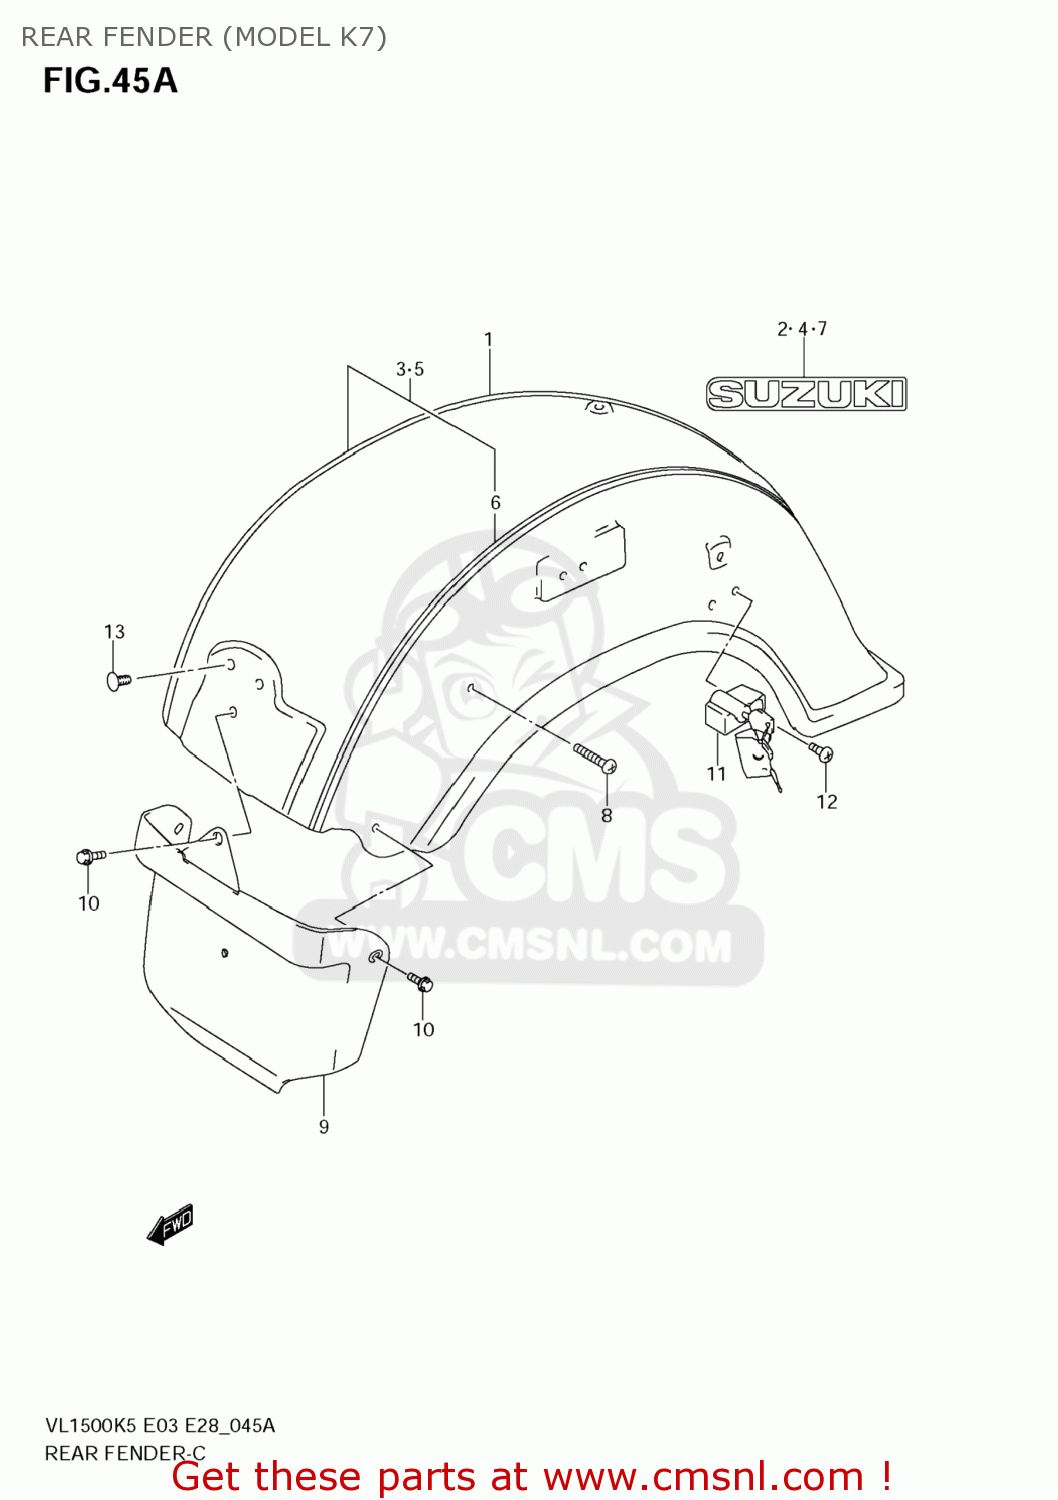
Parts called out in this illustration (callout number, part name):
1	FENDER ASSY,RR
2	EMBLEM,SUZUKI
3	FENDER ASSY,RR
4	EMBLEM,SUZUKI
5	FENDER ASSY,RR
6	TAPE SET,RR FENDER
7	EMBLEM,SUZUKI
8	BOLT(8X37)
9	MUDGUARD,RR FENDER FR
10	BOLT(6X16)
11	LOCK SET,HELMET
12	SCREW(6X14)
13	CAP(OD:12)
